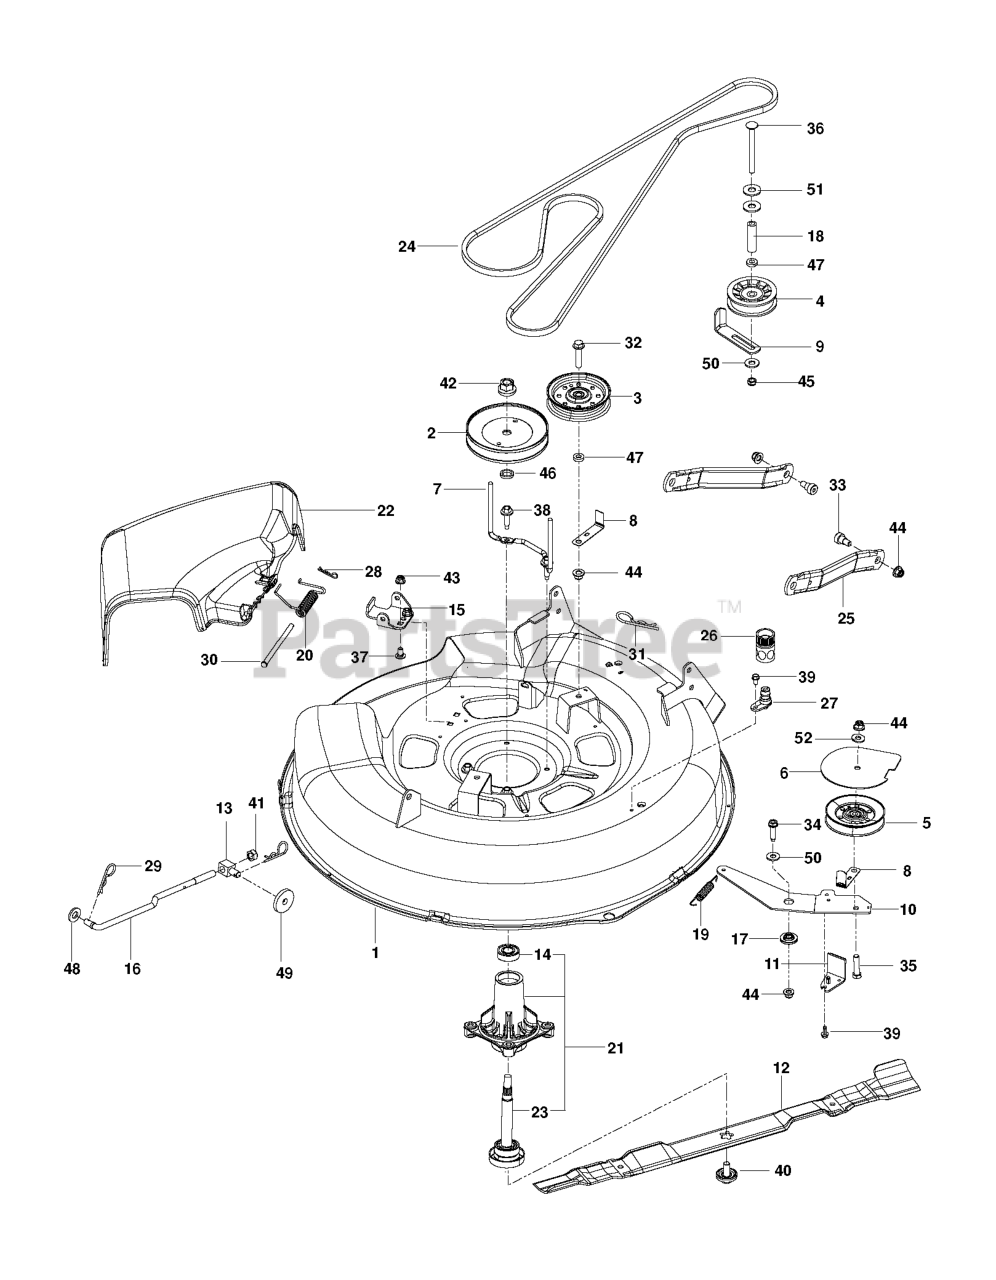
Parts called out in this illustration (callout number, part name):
1	DECK.SVC.W/DECALS.30".RZ.ORN
2	PULLEY MANDREL 5.0"
3	PULLEY.IDLER.FLAT.46.PR.DR.
4	PULLEY, IDLER RAKE & ZTR
5	REPL BY 532 1467-63
6	COVER, PULLEY, BLACK
7	BELT KEEPER.MANDREL.38"COATED
8	KEEPER.BELT.30"SRD
9	GUIDE, BELT
10	ARM.IDLER.30".RZ.X431
11	BRAKE.ARM.LH.38"TEX.COATED
12	BLADE.MOWER.BAGGING.30"
13	SWIVEL.TRUNION.LINK.DECK.FRONT
15	BRKT.DEFLECTOR.38"2005+
16	LINK LIFT SUSP. FRONT MOWER
17	SPACER.RETAINER
18	SPACER .39 ID X 2.25
19	SPRING.BRAKE.RETURN.38"
20	SPRING, TORSION
21	MANDREL.NONGREASEABLE.TALL
22	SHIELD.DEFLECT.MWR.30S.BLACK
23	SHAFT.ASM.MDRL.N/GREASE.38
24	BELT DECK 99.60 EFL
25	ARM.SUSPENSION.MOWER
26	COUPLING.QUICK CONNECT
27	PORT.WASHOUT
28	HAIRPIN #2
29	HAIRPIN #4
30	PIN-CLEVIS 5/16 DIA X 5.19 ZD
31	SPRING.RETAINER.YELLOW.ZINC
32	BLT 3/8-16X1-3/4 WHIZLK ZN SP
33	SB 3/8-16 X 3/8 SKT HD ZD
34	SCREW LT
35	CAP.SCREW.HEX.HD.3/8-16
36	RHSNB 3/8-16 X 4 GR5 ZD
37	BOLT.CARR.5/16-18X5/8.SHORT
38	BOLT.HEX.WASHR.HED.313-18X1.19
39	SCREW
40	BOLT.WASHER.ASM.7/16-2
41	NUT, 7/16-20 HEX NYLOC ZC
42	NUT.FLANGE.LOCK.TOP
43	5/16-18 NYLOC FLANGE NUT
44	NUT 3/8-16 HEX FLG NYLOC ZD
45	NUT
46	WASHER.SPACER.MANDREL
47	WASHER 3/8 X 3/4 X .187 TK
48	WASHER STEEL
49	SPINDLE WASHER
50	RP WASHER 3/8 FLAT
51	WASHER 7/16 FLAT ZD
52	WASHER
